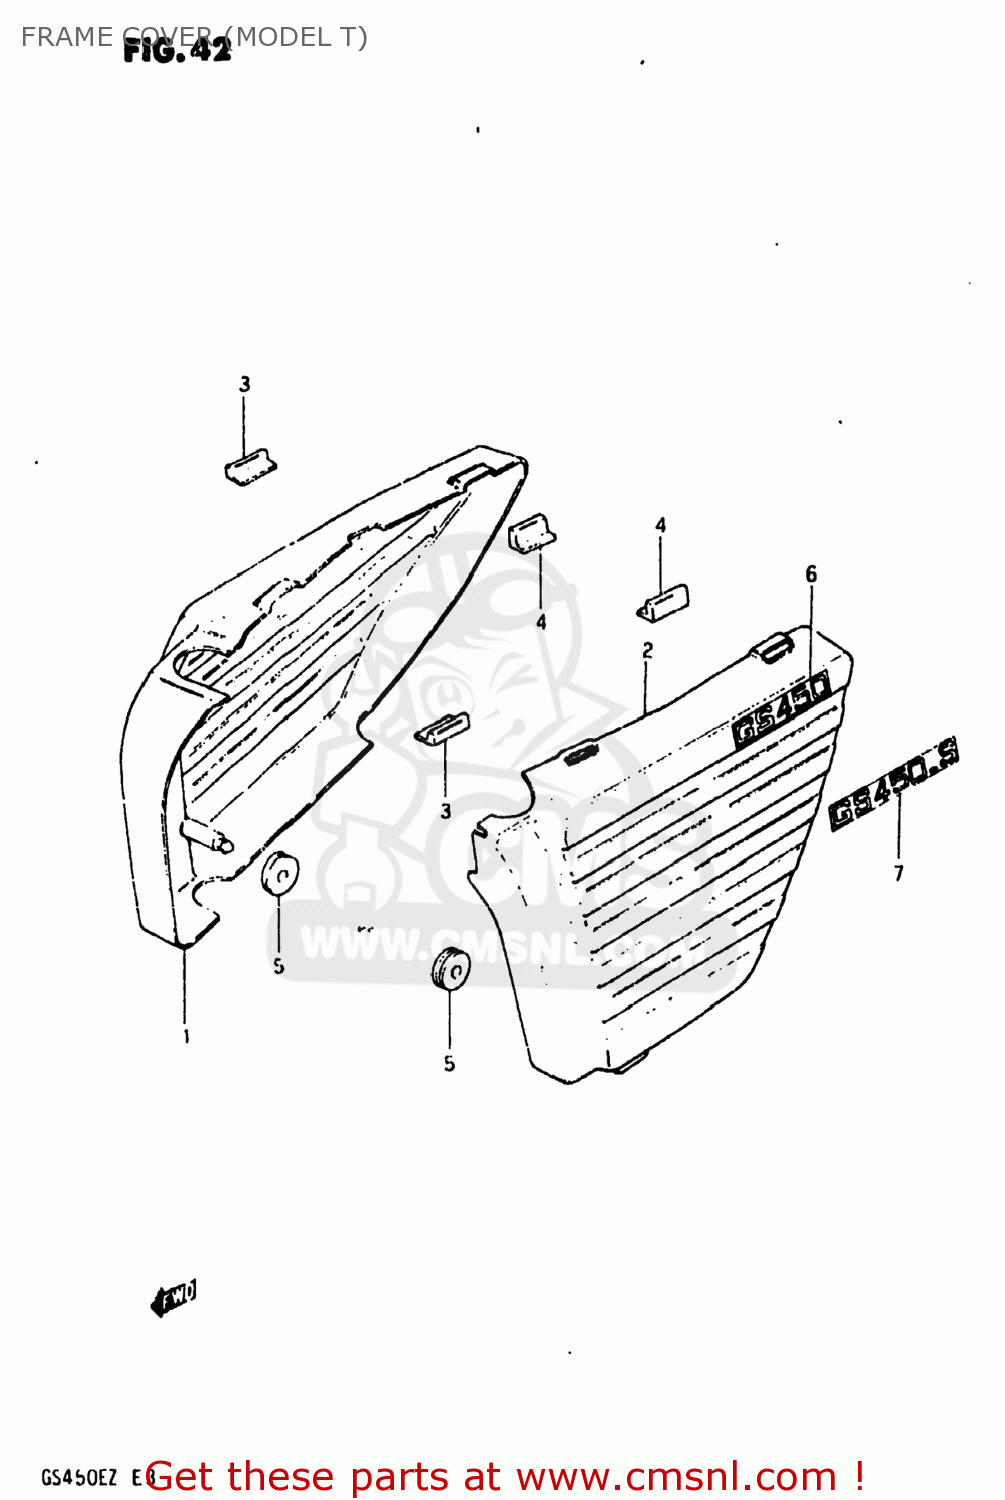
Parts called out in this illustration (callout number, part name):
1	COVER,FRAME,RIGHT
2	COVER,FRAME,LEFT
3	CUSHION,FRAME COVER
4	CUSHION,FRAME COVER
5	CUSHION
6	EMBLEM,FRAME COVER
7	EMBLEM
